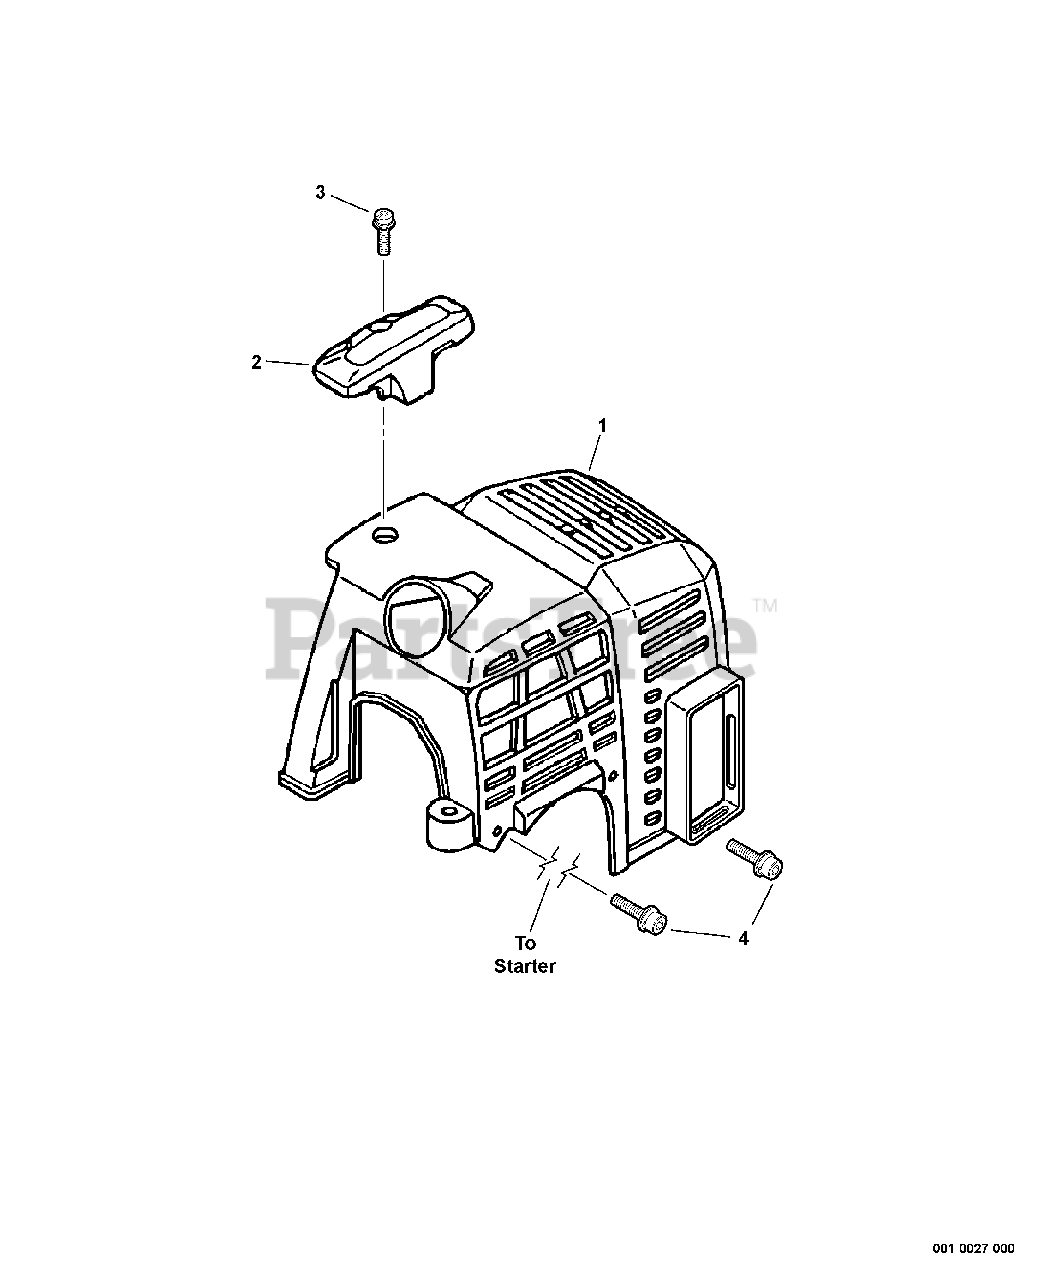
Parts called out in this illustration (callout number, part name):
1	COVER, ENGINE
2	GUARD, TOP
3	SCREW 5×16
4	BOLT 4×16
